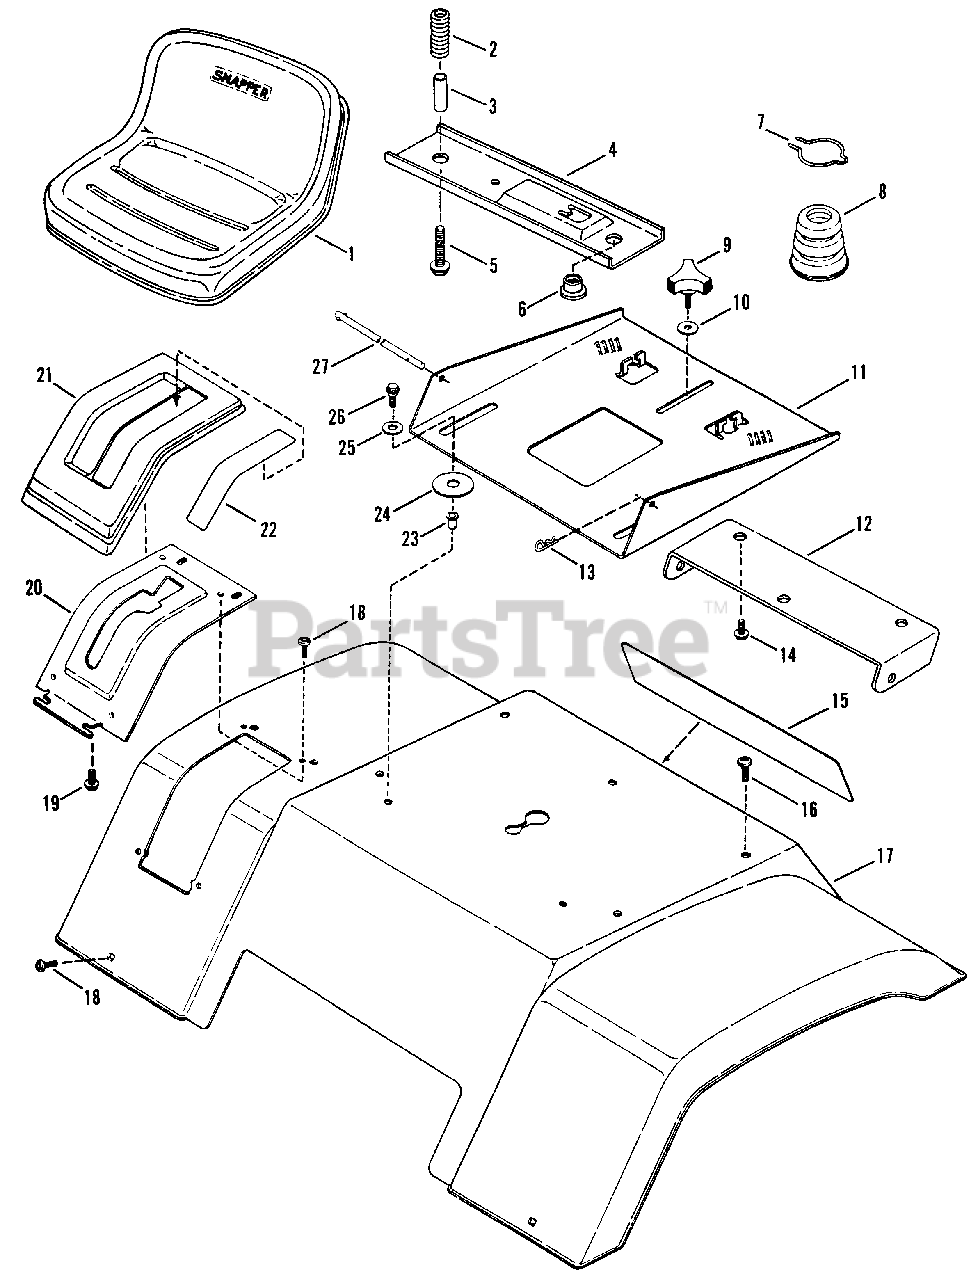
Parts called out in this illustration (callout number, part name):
1	SEAT, Operator's 5 Hole (No longer available)
2	SPRING, Seat Switch
3	SPACER, Seat .467 OD x .328 x 1.375 L
4	HOLDER, Seat Switch
5	BOLT, 5/16-18 x 2" Hex Flange Lock
6	BUSHING, Seat
7	CLIP, Seat Bumper
8	CUSHION, Seat
9	KNOB, 3 Prong 5/16-18 x 3/4
10	WASHER 5/16"
11	SUPPORT, Seat
12	BRACKET, Seat Support
13	PIN, Hair 1.12"
14	BOLT, 5/16-18 x 1/2" Hex Flange Lock
15	DECAL, SNAPPER, Molded Logo 8" - Blue (No longer available)
15	DECAL, SNAPPER, Molded Logo 8" - Green (No longer available
16	SCREW, 5/16-18 x 7/8" Torx Head, Self-Tapping
17	FENDER, Rear
18	SCREW, 1/4-20 x 5/8" Torx Head, Self-Tapping
19	SCREW, #10-16 x 1/2" Self-Tapping
20	DETENT, Shift
21	COVER, Shift Detent
22	DECAL, Shift Cover
23	RIV-NUT, 5/16-18
24	SPACER, WEAR Nylon 2.0 x .62 x .055
25	WASHER, Flat .445 x 1.0 x .059
26	SCREW, Shoulder, 5/16-18 x 3/4"
27	ROD, Seat Hinge
